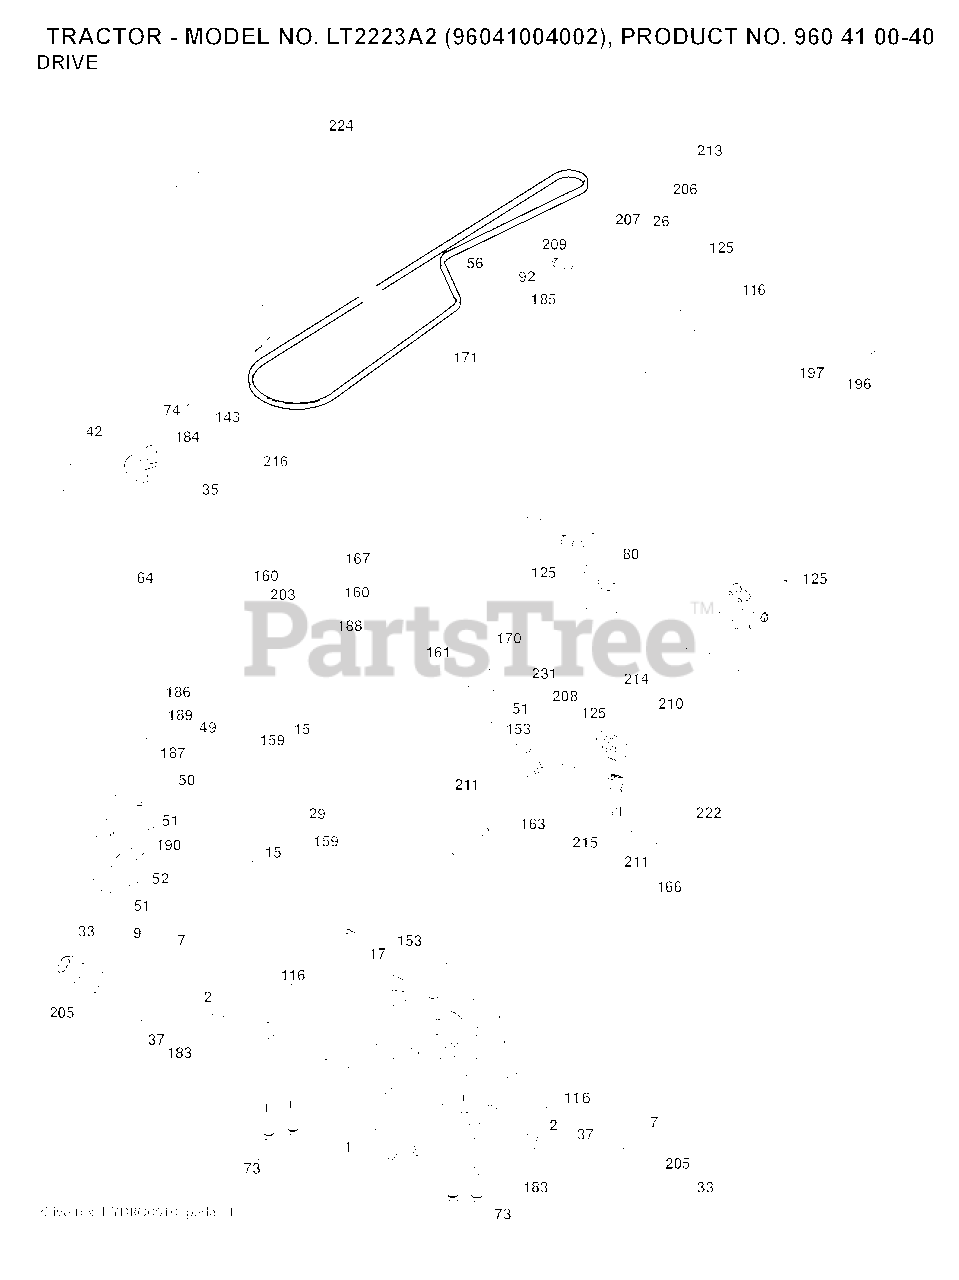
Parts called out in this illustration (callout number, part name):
2	KEY.SQUARE.187X2.500
7	HUB.ASM.WHEEL.REAR.22"
9	HUB BOLT
17	SPRING.BRAKE.K46.GREEN
26	SPRING.RETURN.CRUISE
29	ROD.BRAKE.K46
33	E-RING LT
35	ROD.BRKAE.PARKING.STEALTH
42	PEDAL COVER T
49	BOLT
50	IDLER.FLAT.910.OFFSET
51	NUT LOCK FLG 3/8-16 UNC
52	IDLER.V-GROOVE.910.OFFSET
64	SHAFT.ASM.PEDAL.BRK.CNTR
73	BOLT HEX 5/16-18 GR 5
74	SCREW.HI-LO.CONSOLE
80	STRAP TORQUE
92	BOLT
99	ROD.SPRING.BYPASS.K46.LT.Z
116	NUT LOCK HEX FLANGE 5/16-18
125	SCREW
143	SCREW LT
153	RETAINER M
159	COTTER PIN
160	RETAINER CLIP
161	SPRING, RETURN LT
163	ROD.CONTROL.PEDAL.K46
166	NUT.PUSH.625.2006
167	LATCH.BRAKE.SPRING
170	KEEPER.CENTER SPAN.1.688
183	SPACER.SPLIT.800X.350
184	HANDLE.PRKG.BRAKE.STLTH.TX.RED
185	BOLT
186	SPACER.RETAINER
187	WASHER 12/32X2X10GA
188	LINK.CLUTCH.GROUND.DRIVE
189	BELLCRANK.GROUND.DRIVE.TEX.
190	KEEPER.BELLCRANK.DRIVE
196	SCREW 3/8-16X1
197	BRKT.ANIT-ROTATION.CLU
206	BRKT.MOUNT.LATCH.CRUIS
207	LATCH.CONTROL.CRUISE
208	GEAR.SECTOR.CONTROL.CR
209	ROD.CONTROL.CRUISE.STEALTH.TEX
210	ROCKER.ASM.PEDAL.CONTR
211	BEARING.NYLON
213	KNOB.CONTROL.CRUISE
214	PEDAL.FORWARD.TEX.GT.4
215	PEDAL.REVERSE.TEX.GT.4
216	BRACKET.PULLEY.IDLER.W/TEX
221	RETAINER.SPRING.CLIP.H
222	WASHER 21/32 X 1-1/4 X 10 GA.
224	CONSOLE.TOOLBOX.PCH.ERGO.BLACK
225	KEEPER.BELT.TRANSAXLE.K46
226	BRACKET.MOUNT.TORQUE.K46.TLT
230	WASHER.HARDENED
231	IDLER.V-GROOVE.1.688.OFFSET
